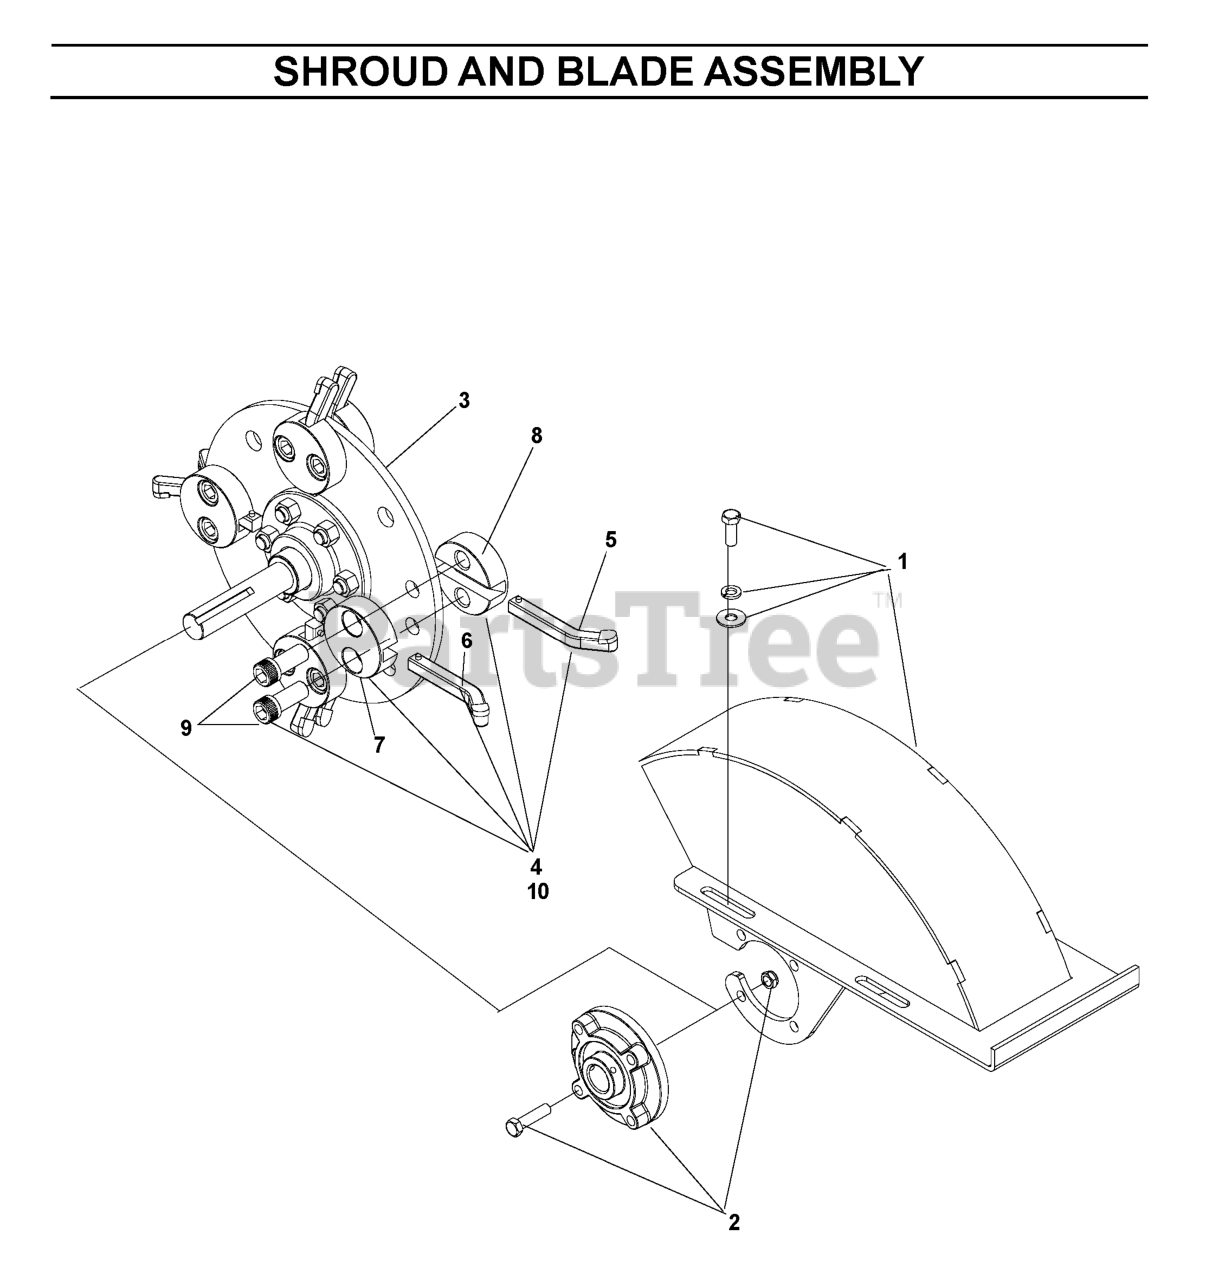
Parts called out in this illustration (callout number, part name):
1	CUTTING SHROUD W/DECAL
2	BEARING KIT STUMPGRINDER
3	KIT CUTTING WHEEL
4	KIT, CUTTING TEETH SET, S G
5	KIT LEFT TOOTH STUMP GRINDER
6	KIT RT TOOTH STUMP GRINDER
7	KIT, COUNTER BORE POCKET
8	KIT, THREADED POCKET
9	KIT POCKET BOLTS STUMP GR
10	KIT CUTTING TEETH COMPLETE
